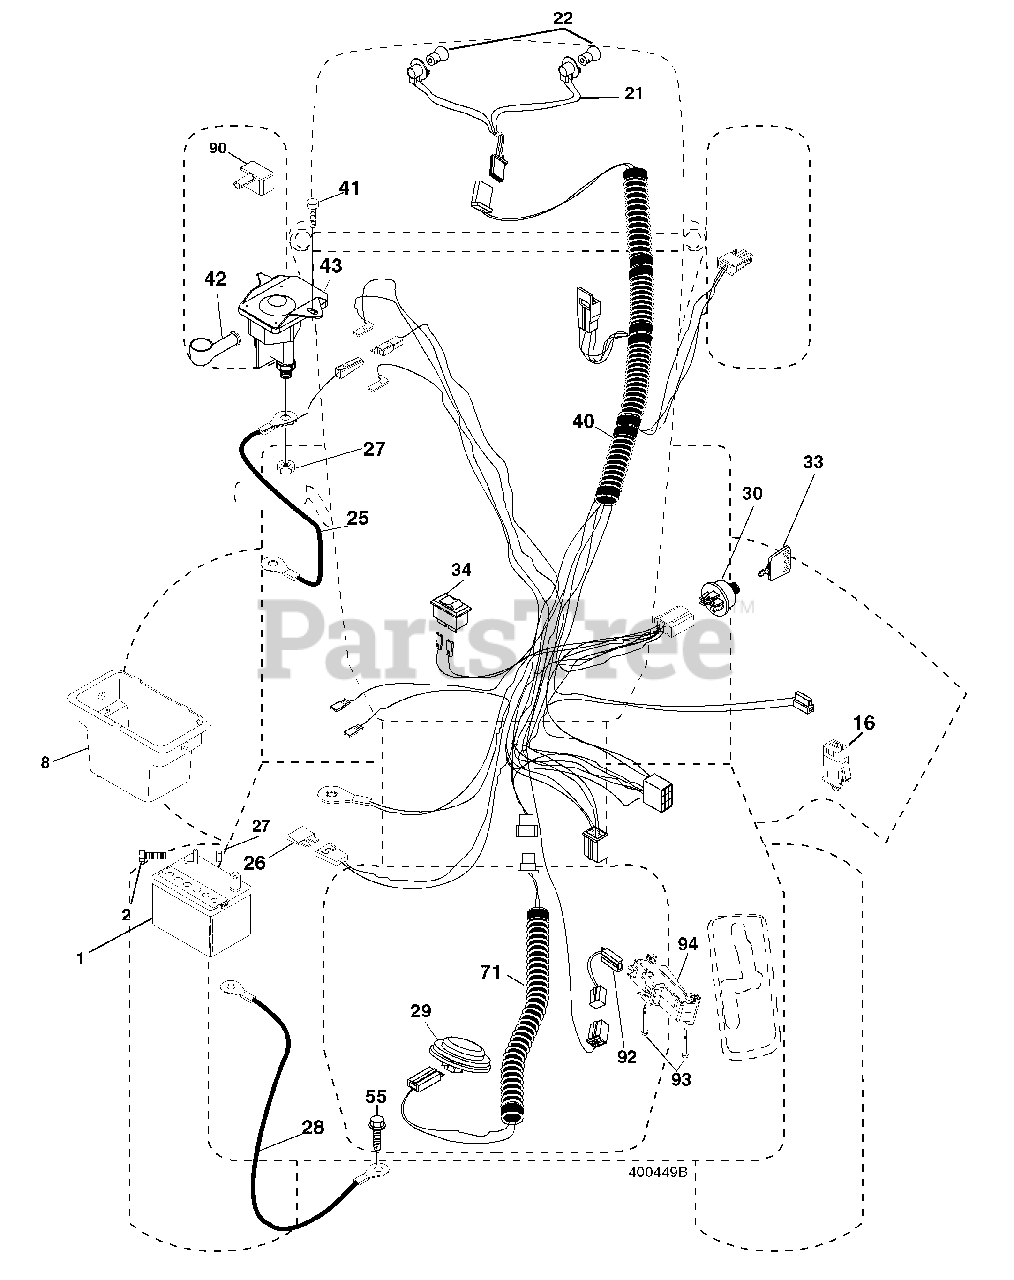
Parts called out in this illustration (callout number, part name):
2	Bolt Hex Hd 1/4-20 unc x 3/4
8	Box Battery
16	Switch Interlock
21	Harness Socket Light
22	Bulb, Light # 1156
25	Cable Battery 6 Ga. Red 14.5
26	Fuse
27	Nut Keps Hex 1/4-20 unc
28	Cable Ground 18" Rear Battery Blk 6 Ga.
29	Switch Seat
30	Switch Ign
33	Key Ign Molded Generic
34	Switch Light/Reset
40	Harness Ign
41	Screw 1/4-20 unc x 1/2
42	Cover Terminal Red
43	Solenoid
55	Screw 5/16-18 x 3/4
71	Harness Ign. Chass.
90	Cover Terminal
92	Harness Pigtail Reverse Switch
93	Screw Plastic 10-14 x 2.0
94	Modual Reverse ROS
